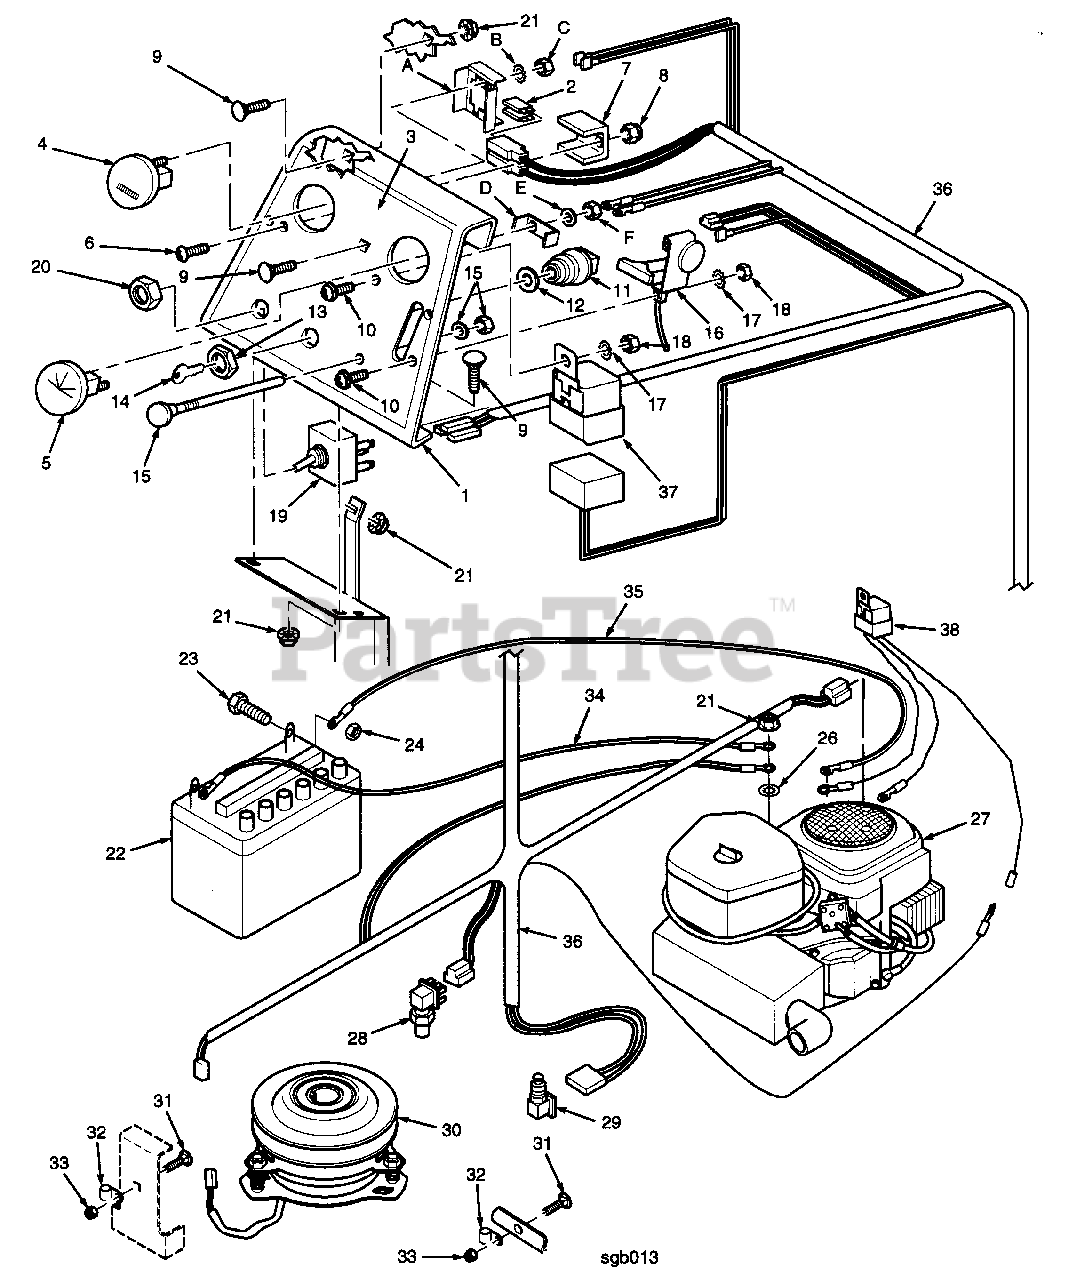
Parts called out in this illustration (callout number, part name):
1	INSTRUMENT PANEL(INCLUDES DECAL)
2	BLADE FUSE, 20 AMP.
3	DECAL, INSTRUMENT PANEL
4	HOUR METER(INCLUDES BRACKET&HARDWARE A,B,C,)
5	AMMETER(INCLUDES BRACKET AND HARDWARE D,E,F)
6	PHILLIPS RD. HEAD SCREW, #10-32 X 1-1/2
7	BRACKET, FUSE HOLDER
8	ELASTIC STOP NUT, #10-32
9	CARRIAGE BOLT, 5/16-18 X 3/4
10	PHILLIPS WASHER HEAD SCREW, #10-32 X .50
11	KEYSWITCH
12	LOCKWASHER, 5/8 INT. TOOTH
14	IGNITION KEY AND RING ASSY.
15	CHOKE CONTROL(INCLUDES HARDWARE)
16	THROTTLE CONTROL
17	LOCKWASHER, #10 EXT. TOOTH
18	HEX NUT, #10-32
19	SWITCH, PTO
21	SERR. FL. HH NUT, 5/16-18
22	BATTERY
23	BOLT, HEX HEAD 1/4-20 X 1/2
24	HEX NUT 1/4-20
26	LOCKWASHER 5/16 INT. TOOTH
27	ENGINE, 20 HP KOHLER CV
27	ENGINE, 22 HP KOHLER CV
28	SWITCH, PARKING BRAKE
29	SWITCH, FOOT SAFETY
30	CLUTCH, ELECTRIC
31	CARRIAGE BOLT, 5/16-18 X 3/4
32	WIRELOOM
33	LOCKNUT, ELASTIC STOP 5/16-18
34	BATTERY CABLE, 36" BLACK
35	BATTERY CABLE, 25" RED
36	WIRE HARNESS, STHM
37	RELAY
38	WIRE HARNESS WITH RELAY
